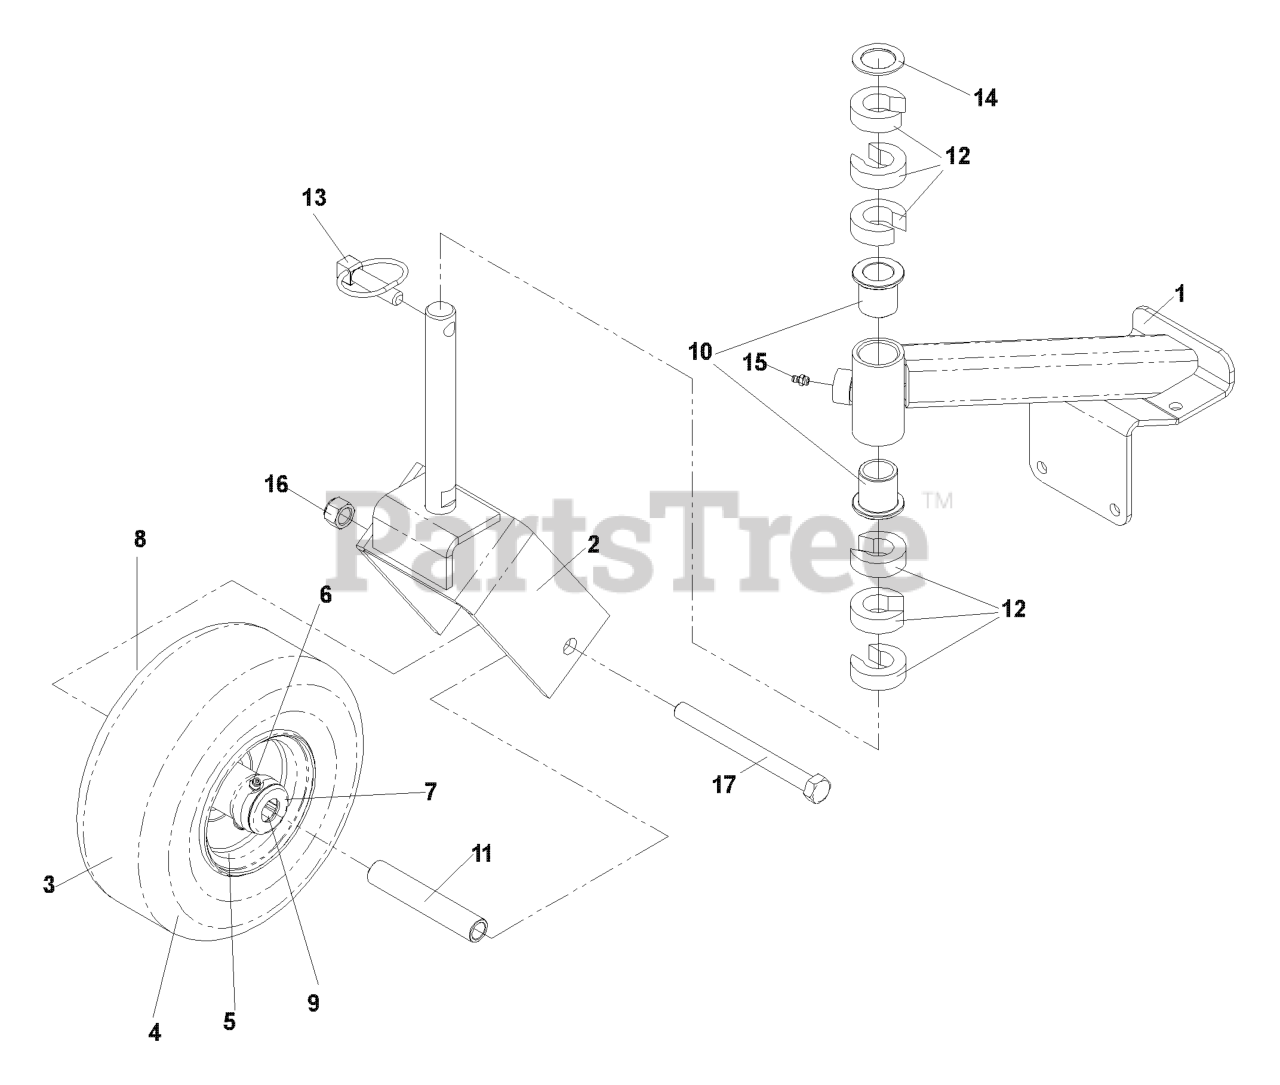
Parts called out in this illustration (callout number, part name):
1	CASTER ARM W/ BUSHING
2	CASTER FORK, ORANGE
3	TIRE/WHEEL.CASTER.9X3.5-4.SMOO
4	TIRE 9 X 3.5 - 4
6	GREASE ZERK
7	ENDCAP
8	ENDCAP, NOTCHED
9	ROLLER BEARING
10	BUSHING, FLANGED
13	LYNCH PIN 7/16
14	MACHINE BUSHING
15	ZERK
16	NUT 1/2-13 HEX NYLOC ZD
17	HCS 1/2C X 5 1/2
